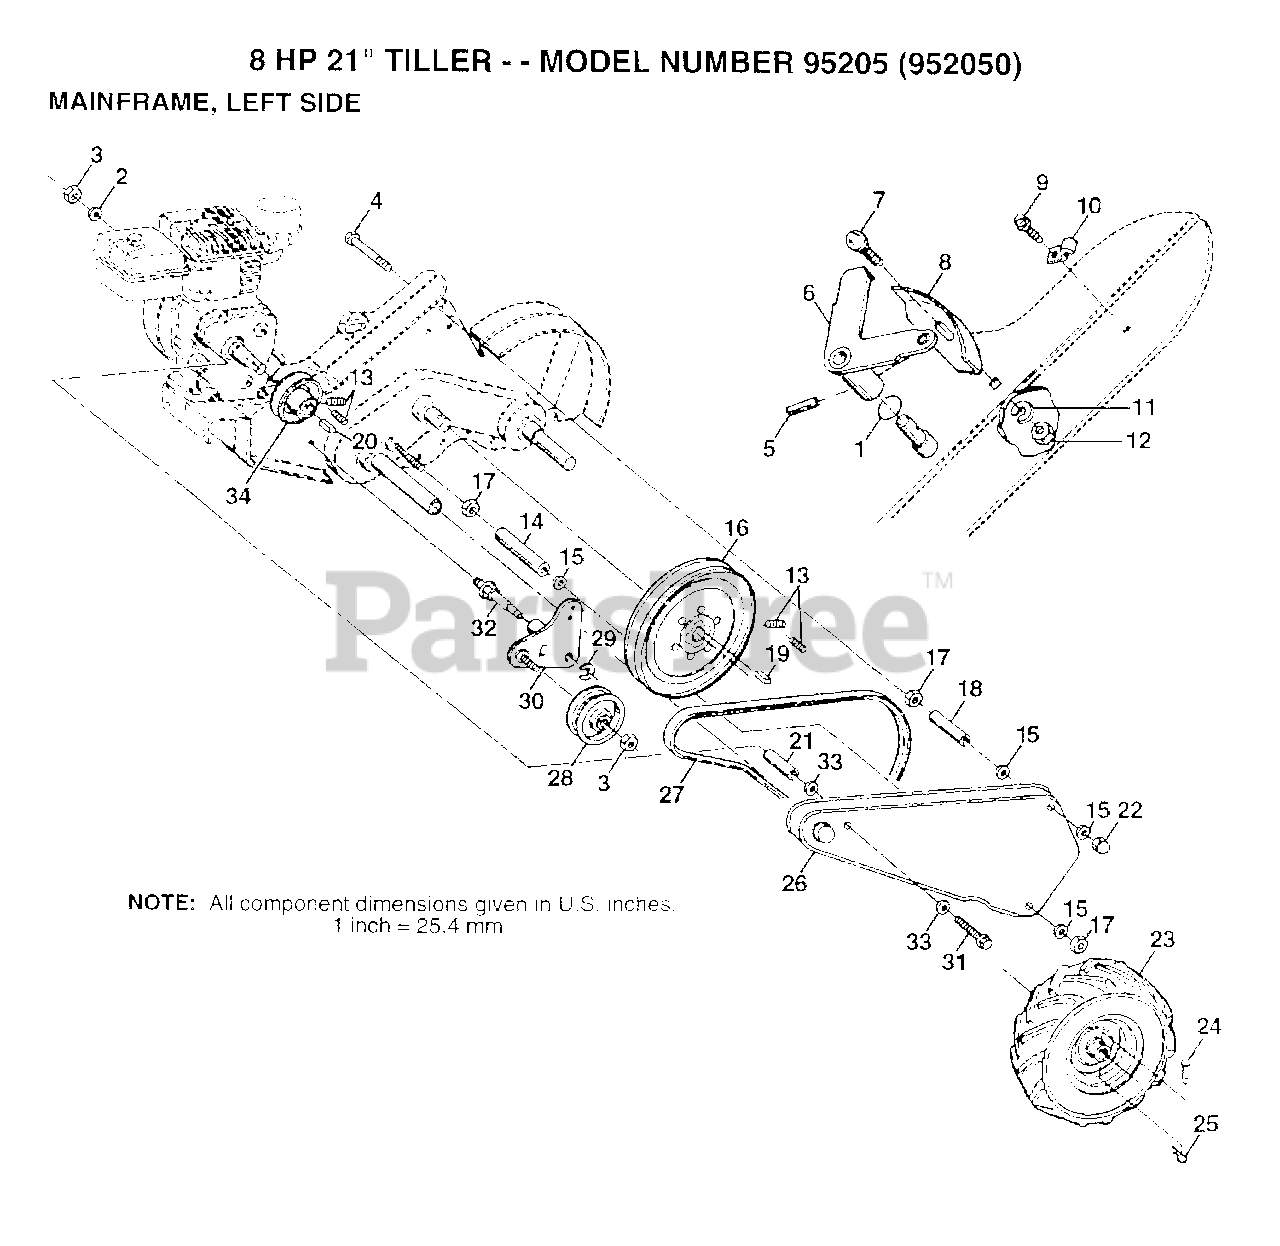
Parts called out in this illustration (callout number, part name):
1	O-RING TI
2	LOCKWASHER
3	NUT.HEX.3/8-16UNC
4	BOLT TI
6	LEVER.ASM.SHIFT
7	BOLT
8	PANEL TI
10	CONDIUT CLIP T
11	LOCKWASHER
13	SET SCREW
14	SPACER TI
15	WASHER
16	"SHEAVE 10"" CRT"
17	NUT.HEX.5/16-18
18	SPACER TI
19	KEY T
20	KEY TI
21	SPACER.SPLIT
22	NUT TI
23	TIRE TI
24	RIVET.PAN HD.1.75
25	SPRING.RETAINER
27	BELT.DRIVE
29	KLIP RING
34	SHEAVE CRT
